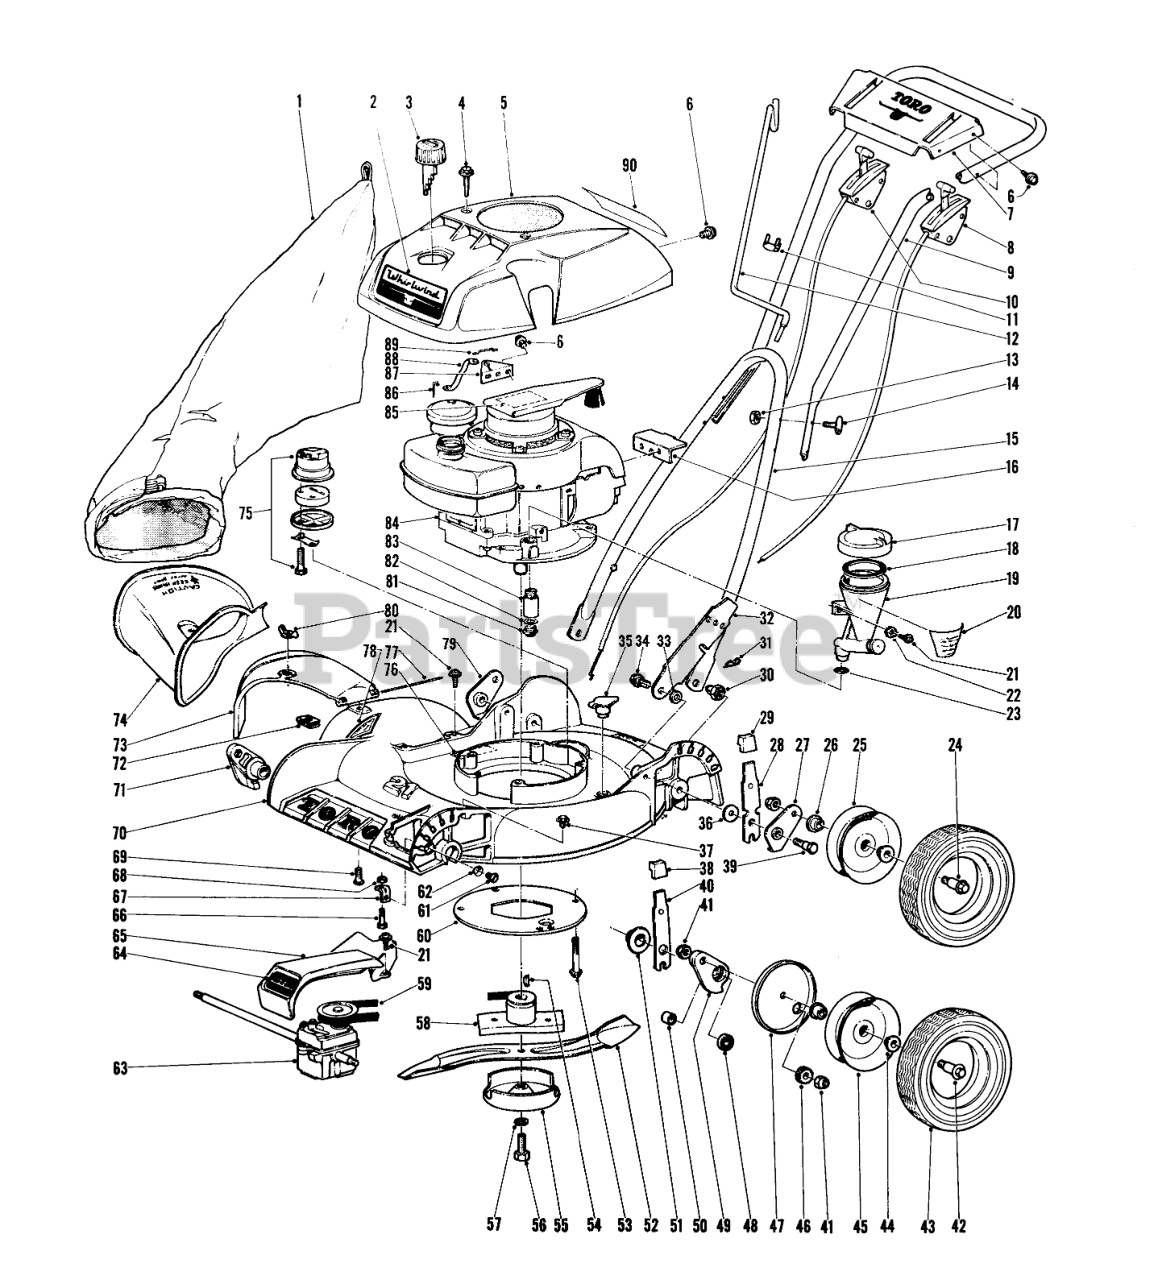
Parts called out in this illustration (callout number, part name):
1	Bag-Set of 2
2	Decal
3	Gas Cap
4	SCREW-HWH
5	Shroud
6	SCREW-HWHTF
7	Plate, Escutcheon
8	Traction Control
9	Handle-Upper
10	Assembly, Throttle Control
11	CONTROL WIRE CLIP
12	GRASS BAG HANGER
13	Nut
15	Handle-Lower
16	Bracket
17	Reservoir Cap w/Ring
18	"O" Ring
19	Reservoir, Oil
20	Decal, Reservoir
21	Screw
22	Washer
23	O-RING
25	Wheel (Incl. Ref. 25)
26	Bushing
27	Pivot Arm
28	Spring Arm
30	Nut
31	PIN-COTTER, HAIR
32	Latch
33	SPACER
34	SCREW-SHOULDER
35	Washer Plug
36	Washer
37	SCREW-HHF
38	ARM KNOB
39	5/16-18 PIVOT SCREW
40	Spring Arm
41	NUT-HEX
42	Wheel Bolt
43	8 TIRE
44	Bushing
45	Wheel Assembly
46	PINION GEAR
47	WHEEL COVER
48	.375 RPP BALL BEARING
49	LH PIVOT ARM & BSHG
50	BUSHING
51	End Cap
52	Blade
53	Screw
54	KEY-WOODRUFF
55	Scalp Cup
56	SPECIAL SCREW
57	WASHER-LOCK
58	BLADE RETAINER WA
59	Belt
60	Grass Guard
62	Lockwasher
63	Gear Case Assv.
64	Decal
65	Guard, Belt
66	SCREW
67	ADJ BRACKET
68	NUT-JAM
70	Housing
71	Arm, Pivot
72	NUT-SPEED
73	Deflector
74	Attachment Bag
75	Muffler
76	Decal
77	HINGE PIN
78	Decal
79	Pivot Arm
80	NUT-WING SPECL
81	Plug Oil Drain
82	Gasket-Oil Drain
83	Extension Oil Drain
84	Engine
85	Decal
87	Pivot, Throttle
88	Rod, Throttle
89	Linkage, Throttle
90	Decal
